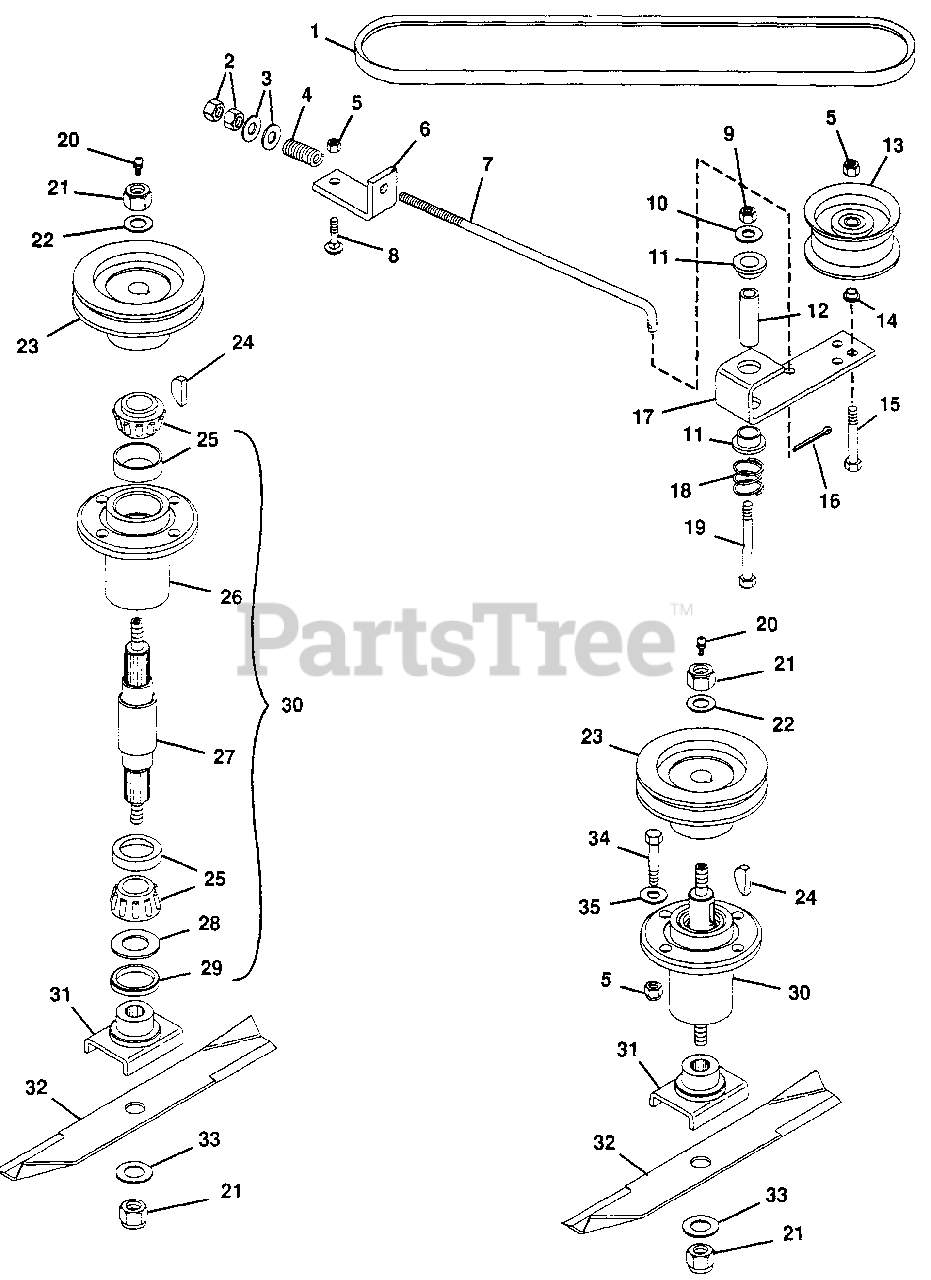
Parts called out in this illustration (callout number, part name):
1	Belt, Pro-36 Mower
2	Nut, Hex 3/8-24
3	Washer, Flat .406x.812x.065
4	Spring, Comp. 1x.78x338 Lb/N
5	Nut, Lock 3/8-16
6	Bracket, Belt Tensioner
7	Rod, Idler
8	Bolt, 3/8-16x1.00 Rd Hd Sq Nk
9	Nut, Lock 1/2-13
10	Washer, Flat .531x1.250x.100
11	Bushing, Flange Nylon
12	Bushing, St. .560x.750x2.44 Stl.
13	Pulley, Idler
14	Bushing, Flange Bronze
15	Bolt, Hex 3/8-16x2.25
16	Pin, Cotter .09x.75
17	Arm, Idler Pivot
18	Spring, Comp. 1x.80x36 Lb/N
19	Bolt, Hex 1/2-13x3.25
20	Fitting, Lube 1/8
21	Nut, Lock 5/8-11
22	Washer, Flat .687x1.312x.122
23	Sheave, Spindle
24	Key, Woodruff 1/4x1 Hard #15
25	Assembly, Bearing
26	Housing, Bearing
27	Shaft, Spindle
28	Washer, Flat .975x1.970x.030
29	Seal, Steel
30	Assembly, Spindle
31	Weldment, Blade Cradle
32	Blade, 36" Mower
33	Washer, Flat .656x1.312x.095
34	Bolt, Hex 3/8-16x1.25
35	Washer, Flat .438x1.000x.083
